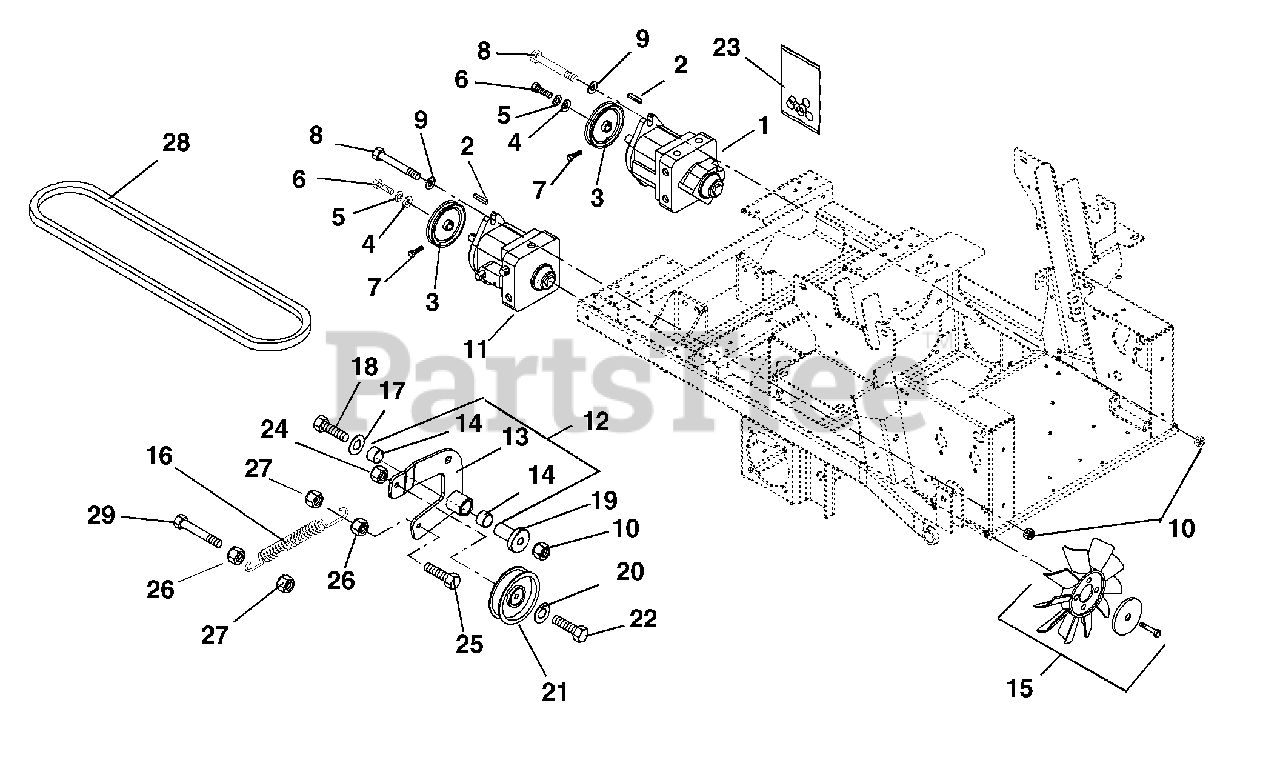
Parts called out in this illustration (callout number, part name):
1	Pump, Hydraulic (RTN) with Auxiliary
2	Key, Square 5 x 5 x 30mm Plain
3	Sheave, Poly-V .671 x 4.125
4	Washer, Flat Steel .25 x 1.0 x .048
5	Washer, Locking .25 x .062
6	Bolt, Hex M6 x 1.0 x 12
7	Screw, Socket Head .25-20 x .50
8	Bolt, Hex .50-13 x 1.50 Grade 5
9	Washer, Flat Steel .531 x 1.06 x .095
10	Nut, Locking Top Flange .50-13
11	Pump, Hydraulic (RTN)
12	Assembly, Idler Arm Guard Drive
13	Weldment, Idler Arm Ground Drive
14	Bearing, 1.00 x 1.12 x .75
15	Fan, Hydro Pump Cooling
16	Spring, Tension .120 x .845 x 6.500
17	Washer, Flat Steel .39 x.75 x.125
18	Bolt, Hex .50-13 x 3.50 Grade 5
19	Bearing, Pedestal Powdered Metal
20	Washer, Flat Steel .406 x .812 x .065
21	Idler, Flat 4.00 x 1.06
22	Bolt, Hex .38-16 x 2.25 Grade 5
23	Kit, Pump Seal
24	Nut, Locking Top Flange .38-16
25	Bolt, Hex .31-18 x 1.25 Grade 5
26	Nut, Hex .31-18
27	Nut, Locking Top Flange .31-18
28	Belt, Poly-V 49.50
29	Bolt, Hex .31-18 x 2.50 Grade 5
